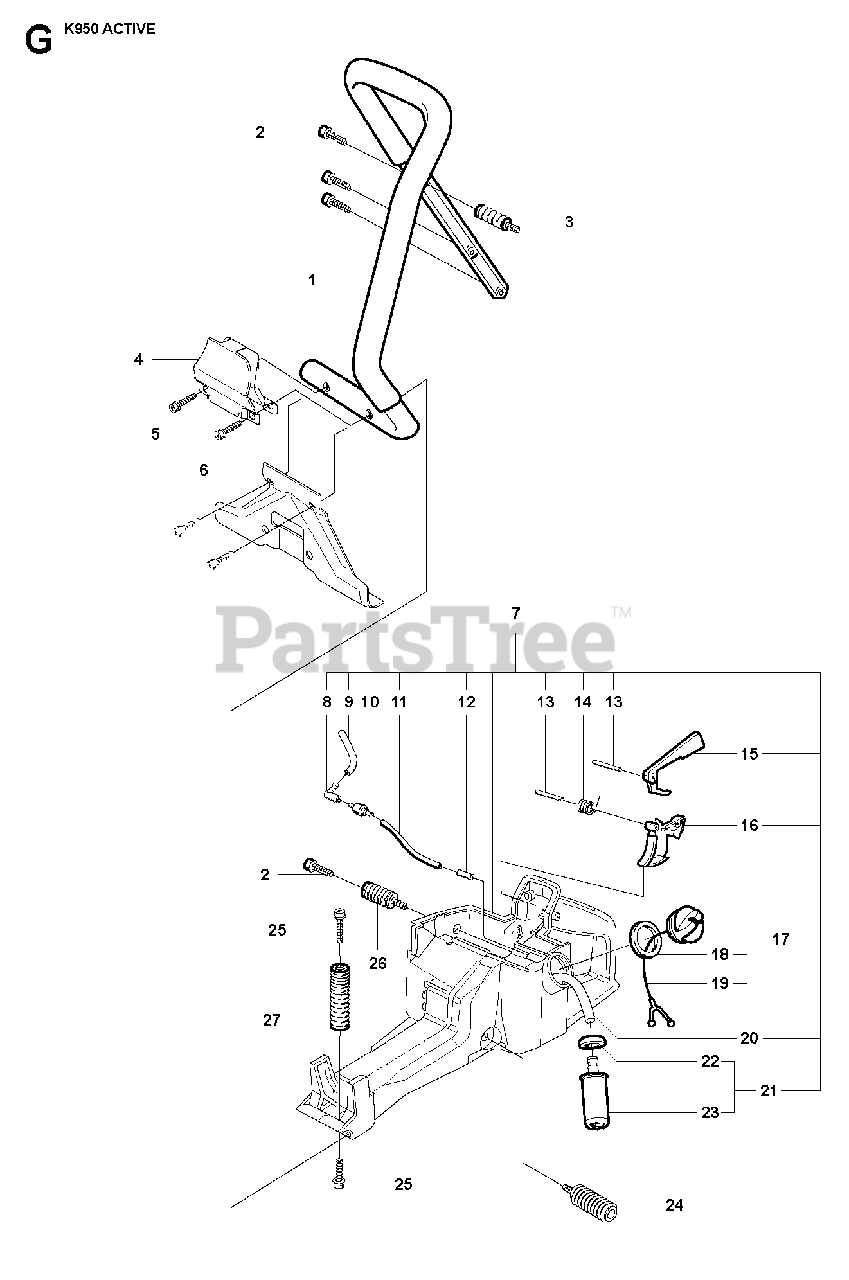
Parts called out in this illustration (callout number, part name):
3	ANTIVIBRATION ELEMENT
6	GROUND SUPPORT"14"", 16"""
7	FUEL TANKIncl. 8 - 16, 20, 21
8	CONNECTION BEND
9	FUEL HOSE
13	PARALLEL PIN
14	SPRING THROTTLE TRIG
15	THROTTLE LOCKOUT
17	TANK CAP ASSYIncl. 18, 19
20	FUEL HOSE
21	FUEL FILTERIncl. 22, 23
25	SCREW IHSCFM
26	ANTIVIBRATION ELEMENT
27	ANTIVIBRATION ELEMENT
